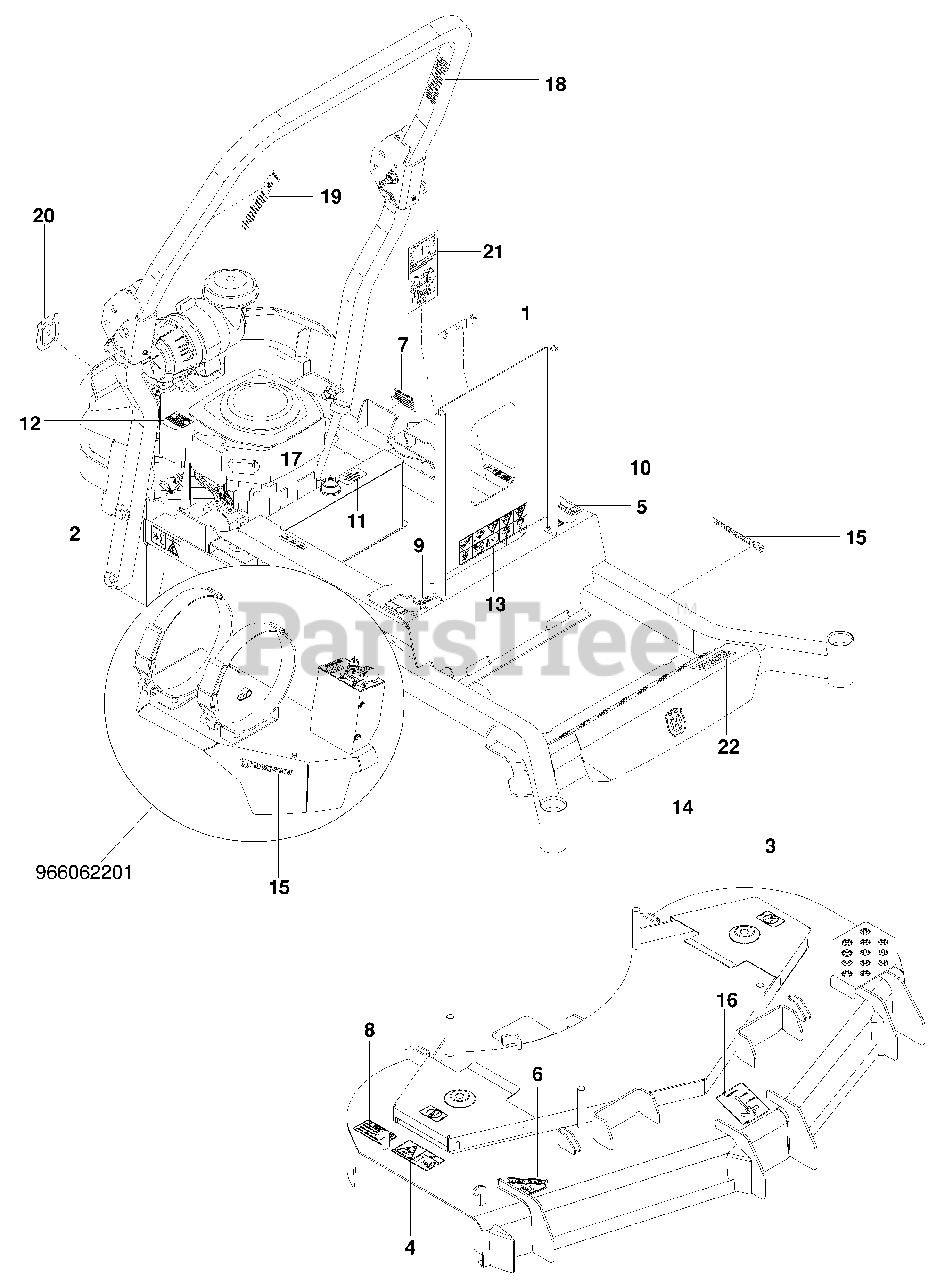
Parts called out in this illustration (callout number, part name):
1	DECAL, BATTERY WARNING
2	DECAL, BELT DRIVE WARN
3	DECAL, NO STEP
4	DECAL, SEVERING
5	DECAL, MOTION CONTROL
6	DECAL, CPSC
7	DECAL, PROP 65
8	DECAL, WARNING
9	DECAL, F.S.T
10	DECAL, PARK BRAKE
11	DECAL, OIL TANK
12	DECAL, EXHAUST
13	DECAL, WARNING
14	DECAL, CROWN H
15	DECAL, HUSQVARNA
16	DECAL, BELT ROUTING
17	DECAL, FUSE
18	DECAL, ROPS
19	DECAL, ROPS WARNING
20	DECAL, CROWN H
21	DECAL, SERVICE
22	DECAL, PZ5426
